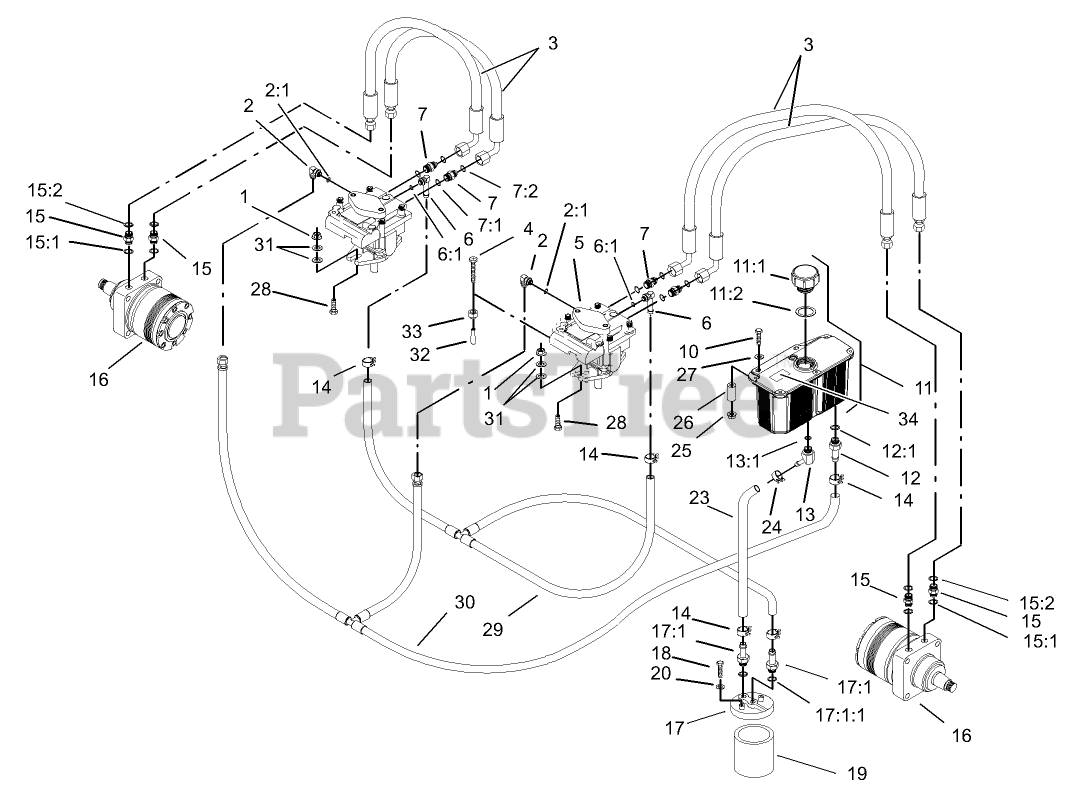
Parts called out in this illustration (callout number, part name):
1	NUT-HHF, WHIZ
2	FITTING-90 DEG
2:1	O-RING
3	HOSE-PRESSURE, HIGH
6	FITTING
6:1	O-RING
7	FITTING-STRAIGHT
7:1	O-RING
7:2	O-Ring
10	SCREW-HH
11	Reservoir-HYD
11:1	CAP-RESERVOIR, HYD
11:2	GASKET-CAP
12	Adapter-Straight
12:1	O-RING
13	FITTING-BARBED, 45 DEG
13:1	O-RING
14	Clamp-Hose
15	Fitting-Straight
15:1	O-RING
15:2	O-Ring
16	HYD MOTOR ASM
17	Filter Head ASM
17:1	ADAPTER-STRAIGHT
17:1:1	O-RING
18	SCREW-HH
19	FILTER-OIL, HYD
20	WASHER-LOCK
23	Hose-Charge
24	Clamp-Hose
25	NUT-HF
26	Spacer
27	WASHER-FLAT
28	SCREW-HH
29	HYD Hose ASM
30	HYD Hose ASM
31	WASHER-FLAT
32	GRIP-VALVE, DUMP
33	NUT-LOCK, NI
34	DECAL-TANK, HYD
